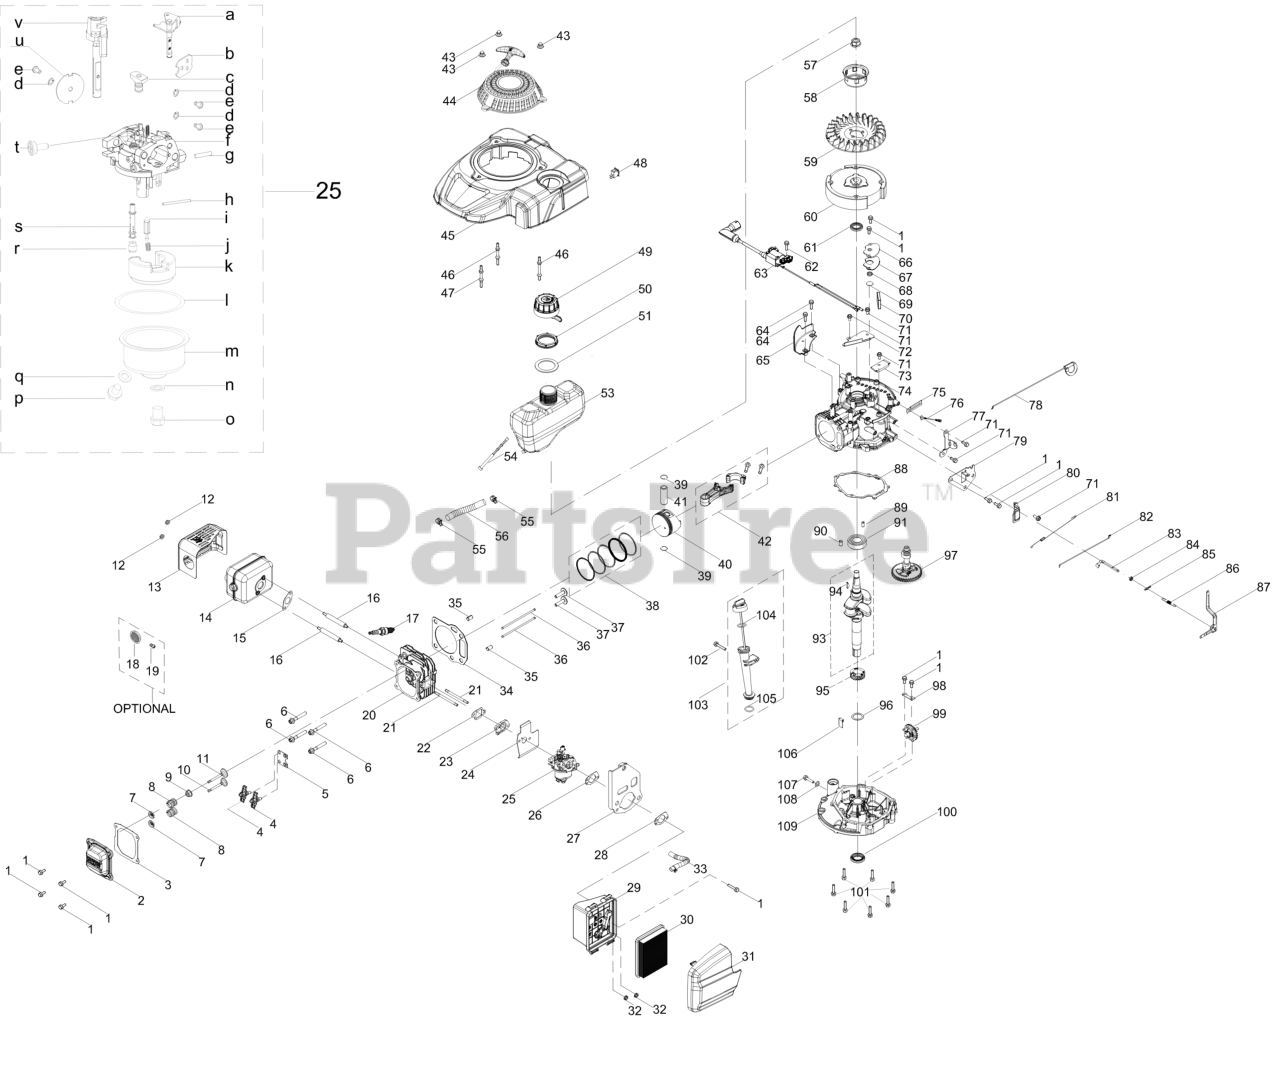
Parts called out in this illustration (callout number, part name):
1	BOLT M6-1 x 14 GR8.8
2	VALVE COVER
3	VALVE COVER GASKET
4	ROCKER ARM ASSEMBLY
5	PUSH ROD GUIDE
6	BOLT-M8 x 54
7	VALVE SPRING RETAINER
8	VALVE SPRING
9	INTAKE VALVE SEAL
10	EXHAUST VALVE
11	INTAKE VALVE
13	MUFFLER SHIELD
15	MUFFLER GASKET
16	STUD M6-1 x 95
17	SPARK PLUG
18	SPARK ARRESTOR
19	SCREW M3.5 x 9.5
20	CYLINDER HEAD
21	CARBURETOR STUD-M6 x 87
22	CARBURETOR INSULATOR GASKET
23	CARBURETOR INSULATOR
24	CARBURETOR GASKET
25	CARBURETOR ASSEMBLY HY-1X65LA
26	AIR FILTER BASE GASKET
27	AIR FILTER BRACKET
28	AIR FILTER BRACKET GASKET
29	AIR FILTER BASE
30	AIR FILTER
31	AIR FILTER COVER
33	BREATHER HOSE ASSEMBLY
34	CYLINDER HEAD GASKET
36	PUSH ROD
37	TAPPET
38	PISTON RING SET
39	SNAP RING-PISTON PIN
40	PISTON
41	PISTON PIN
42	CONNECTING ROD ASSEMBLY
43	ACORN NUT
44	RECOIL STARTER ASSEMBLY
45	ENGINE SHROUD ASSEMBLY
46	STARTER/SHROUD REAR STUD
47	STARTER/SHROUD FRONT STUD
48	IGNITION SWITCH
49	FUEL CAP W/TETHER
50	FUEL TANK NUT
51	FUEL TANK UPPER GROMMET
53	FUEL TANK
54	FUEL FILTER
55	HOSE CLAMP
56	FUEL HOSE
57	FLYWHEEL NUT
58	STARTER CUP
59	COOLING FAN
61	CRANKSHAFT SEAL
62	BOLT M6-1 x 20 GR8.8
63	IGNITION COIL
64	BOLT M6-1 x 25 GR8.8
65	ENGINE BRAKE COVER PLATE
66	BREATHER COVER PLATE
67	BREATHER GASKET
68	BREATHER VALVE SPRING
69	BREATHER VALVE
70	BREATHER SCREEN
71	BOLT M6-1 x 12 GR8.8
72	AIR VANE COVER PLATE
73	GROUND COVER PLATE
75	FLEXIBLE CLAMP
76	GROUND WIRE
77	CHOKE CONTROL BRACKET
78	CHOKE CONTROL
79	COMPONENT BRACKET
80	GOVERNOR SHIELD
81	THROTTLE LINKAGE SPRING
82	THROTTLE LINKAGE
83	GOVERNOR ARM SHAFT
84	GOVERNOR SEAL
85	COTTER PIN
86	GOVERNOR SPRING
87	GOVERNOR ARM ASSEMBLY
88	CRANKCASE COVER GASKET
89	DOWEL PIN
90	DOWEL PIN
93	CRANKSHAFT
94	FLYWHEEL KEY
95	CRANKSHAFT TIMING GEAR
96	THRUST WASHER
97	CAMSHAFT ASSEMBLY
98	GOVERNOR GEAR MOUNTING PLATE
99	GOVERNOR GEAR/SHAFT ASSEMBLY
100	LOWER CRANKSHAFT SEAL
101	BOLT-M6-1 x 28 GR8.8
102	BOLT M6-1 x 35 GR8.8
103	OIL DIPSTICK ASSEMBLY
104	O-RING
106	OIL RETURN SEAL
107	OIL DRAIN PLUG
108	WASHER
109	CRANKCASE COVER
